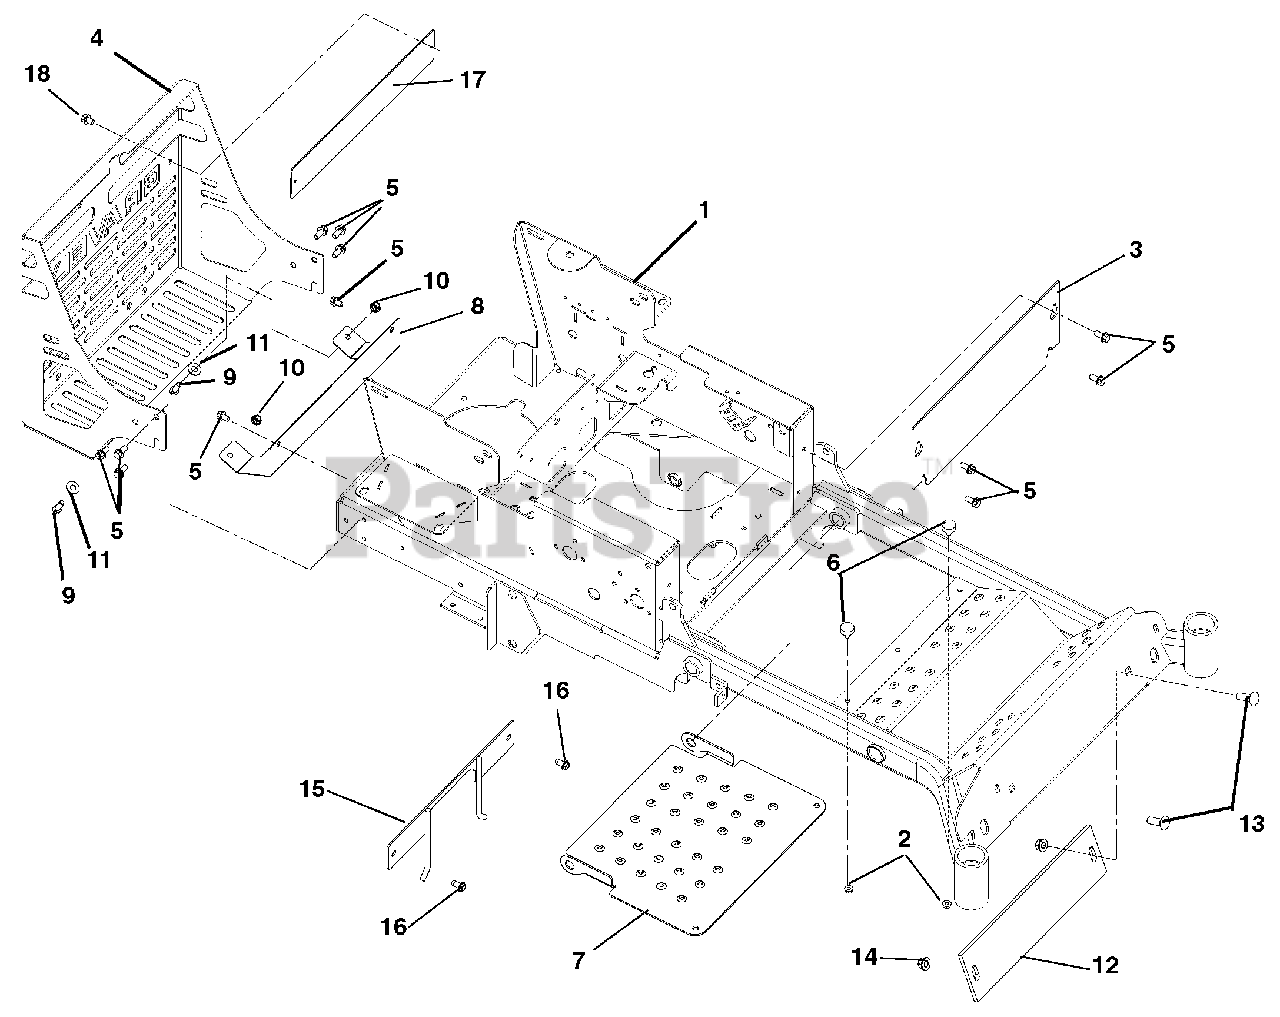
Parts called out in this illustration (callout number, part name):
1	WLDMT, 48" HD FRAME
2	@NUT-SPNLK-FLG .312-18 YWZC
3	PLATE, KICK
4	BUMPER, ARIENS MAX ZOOM
5	@SCR-TAP .38-16X.75 HWH TR YWZ
6	BUMPER, RUBBER
7	PANEL, INSPECTION
8	SHIELD - HEAT - CZ PROD
9	@BLT-HEX .38-16X1.00 GR5 YWZC
10	@NUT-LK-NYL-FLG .38-16 YWZC
11	@WSHR-FL-STL.438X1.00X.083 YWZ
12	COUNTERWEIGHT, CZ FRONT-BLACK
13	BLT-RDHDSQNK .50-13X2.25 G5YZ
14	@NUT-LK-NYL-FLG .50-13 YWZC
15	PTO BELT FINGER WLDMT - BLK
16	@SCR-TAP .38-16X.75 HWH TR YWZ
17	BUMPER BACKER PLATE - BLACK
18	@SCR-TAP .25-20X.50 HWH TR YWZ
